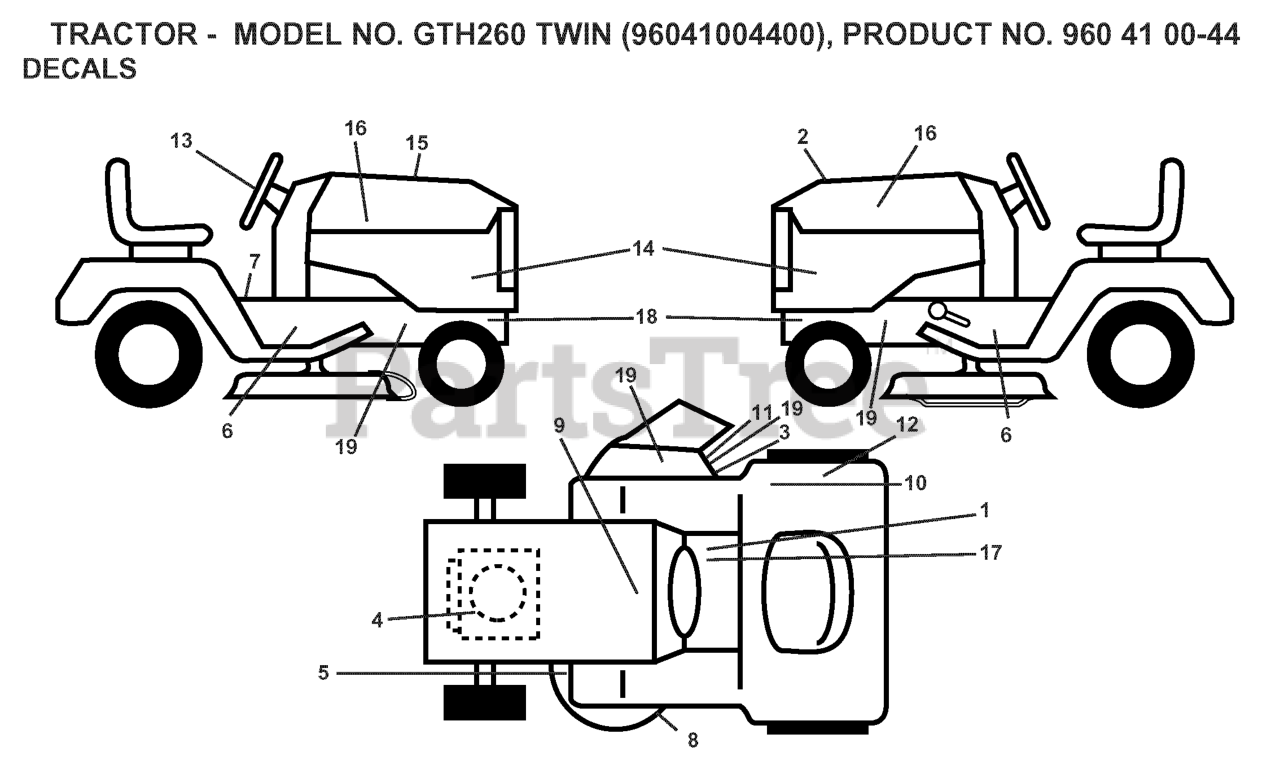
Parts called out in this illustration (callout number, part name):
1	DECAL
2	DECAL.HOOD.TOP.INSERT.
3	DECAL, DEFLECT WARNING
4	DECAL
5	DECAL
7	LABEL
8	DECAL.MOWER.SCH.48/54
9	DECAL BTRY SYMBOLS
10	DECAL.FENDER
11	DECAL.INTERNATIONL.CUTFINGER
12	DECAL
13	DECAL.WHEEL.STRG.LGN.H
16	DECAL.HOOD.NAMELOGO.HUSQ
17	DECAL PARK BRAKE
